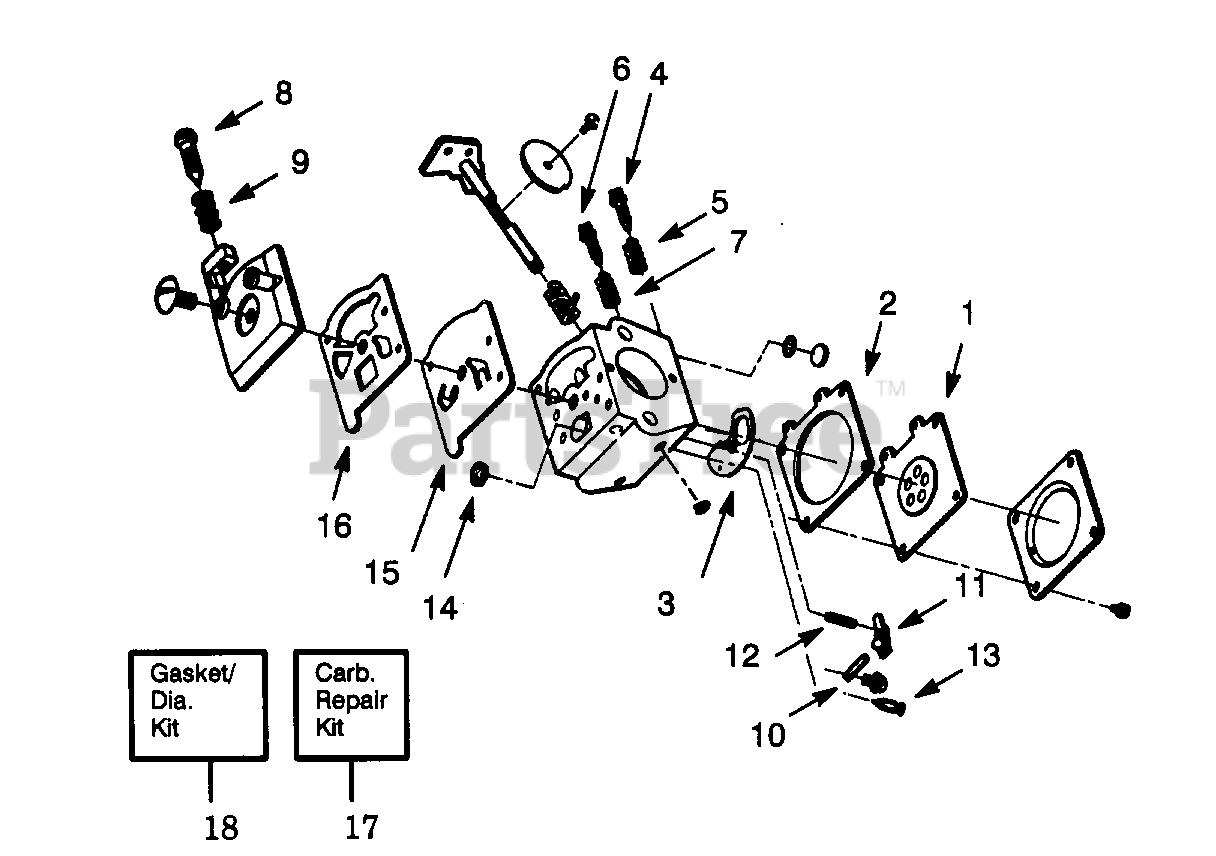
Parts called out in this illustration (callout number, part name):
1	Metering Diaphragm
2	Metering Diaphragm Gasket
3	Circuit Plate Gasket
4	Hi Speed Needle
5	Hi Speed Needle Spring
6	Idle Needle
7	Idle Needle Spring
8	Idle Speed Screw
9	Idle Speed Spring
10	Metering Lever Pin
11	Metering Lever
12	Metering Lever Spring
13	Inlet Needle Valve
14	Inlet Screen
15	Pump Diaphragm
16	Pump Gasket
17	Carb. Kwik Repair Kit
18	Carb. Gasket/Diaphragm Kit
